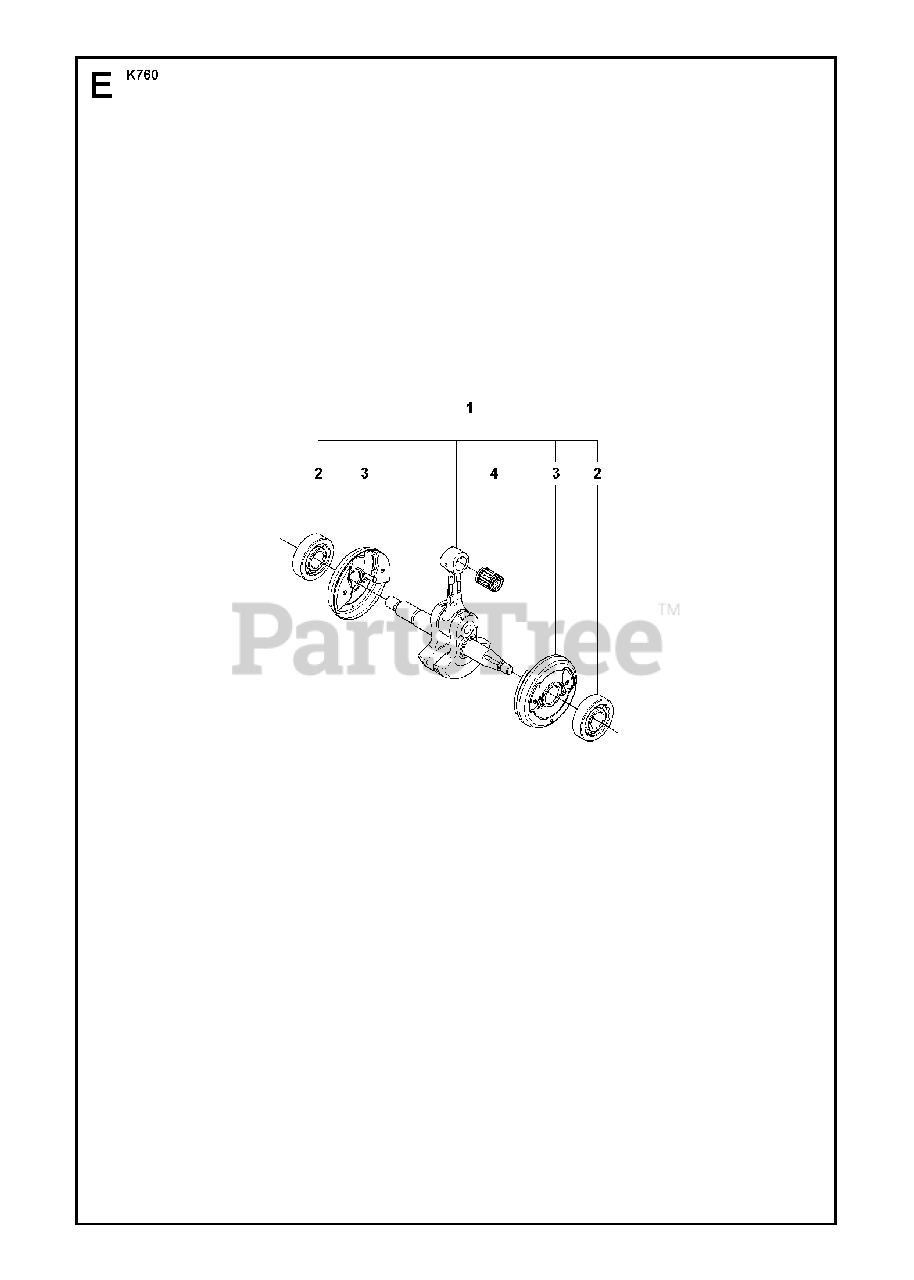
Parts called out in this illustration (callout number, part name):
1	CRANKSHAFT ASSYIncl. 2 - 4
2	BALL BEARING
4	NEEDLE BEARING
